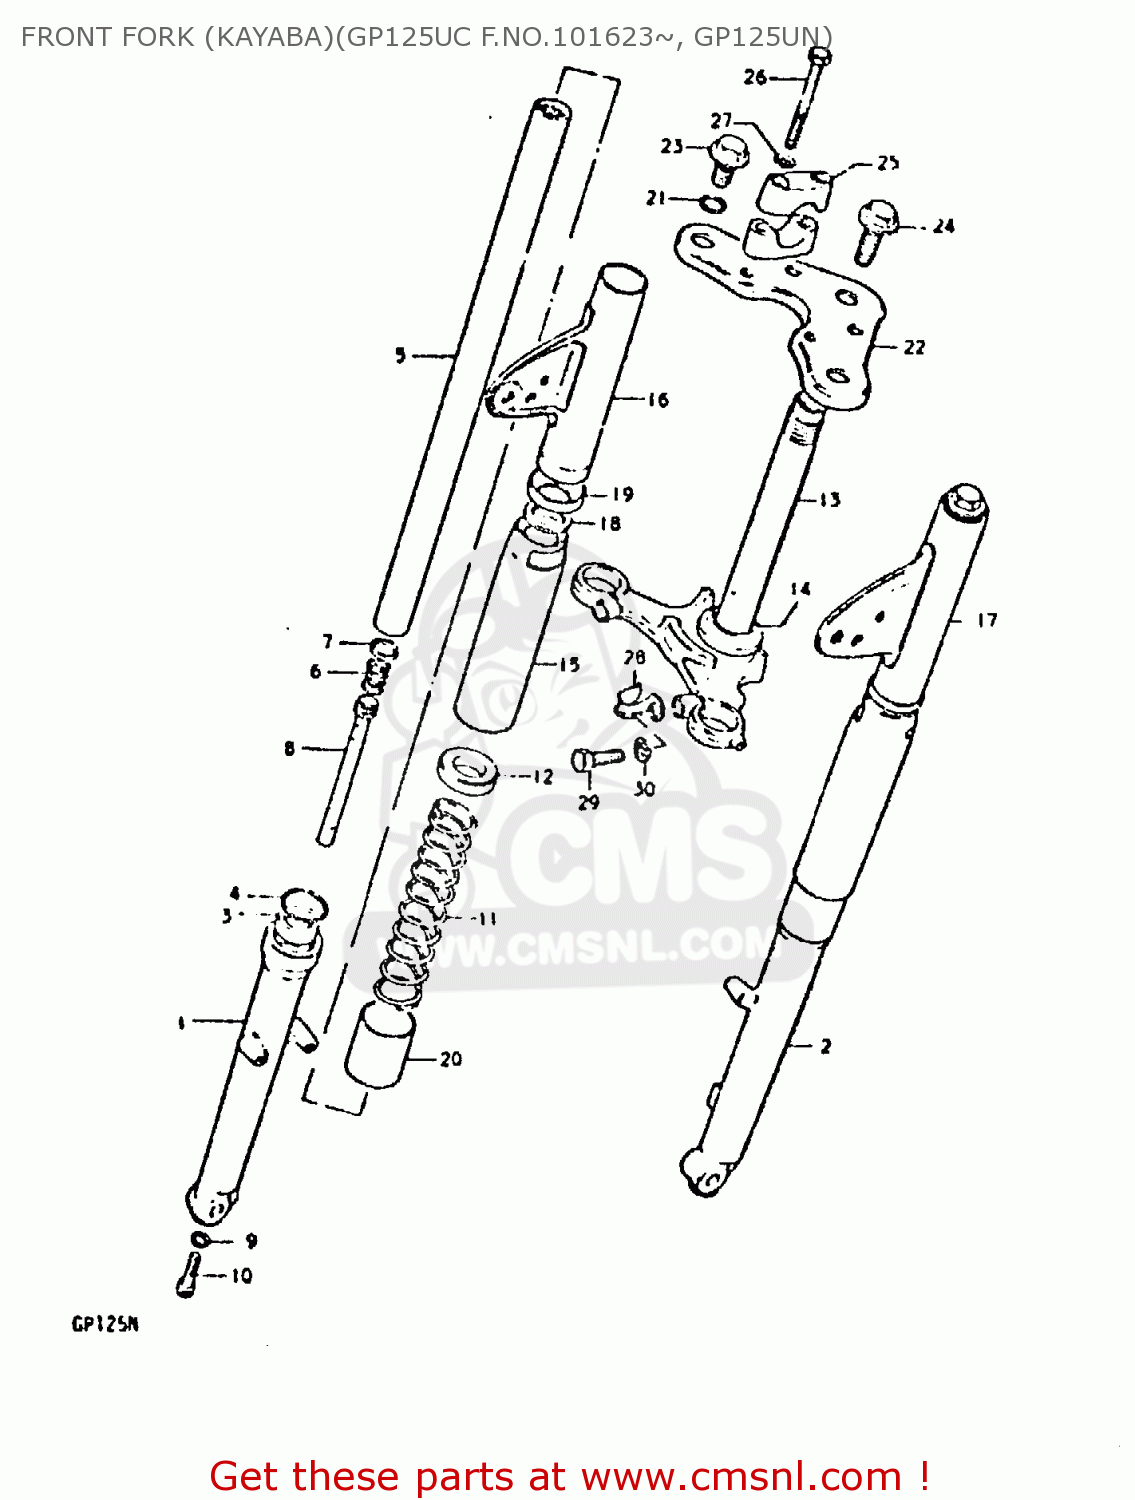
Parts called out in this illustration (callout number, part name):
1	OUTER TUBE, RH
2	OUTER TUBE, LH
3	SEAL,OIL
4	RING,SNAP
5	TUBE, INNER
6	SPRING
7	RING
8	CYLINDER
9	GASKET (NAS)
10	BOLT,FORK CYLINDER(10X25)
11	SPRING
12	GUIDE, SPRING
13	STEM, STEERING
14	RACE,STEERING OUTER LWR
15	COVER, OUTER
16	BRACKET, HEADLAMP RH
17	BRACKET, HEADLAMP LH
18	GASKET (NAS)
19	COVER,GUIDE
20	COVER, OUTER TUBE
21	O-RING,FORK INNER TUBE
22	HEAD, STEERING STEM (BLACK)
23	CAP
24	BOLT
25	HOLDER,HANDLE UPR
26	BOLT 8X55
27	LOCK WASHER
28	CLIP,SPEEDOMETER CABLE
29	BOLT 10X30
30	LOCK WASHER
